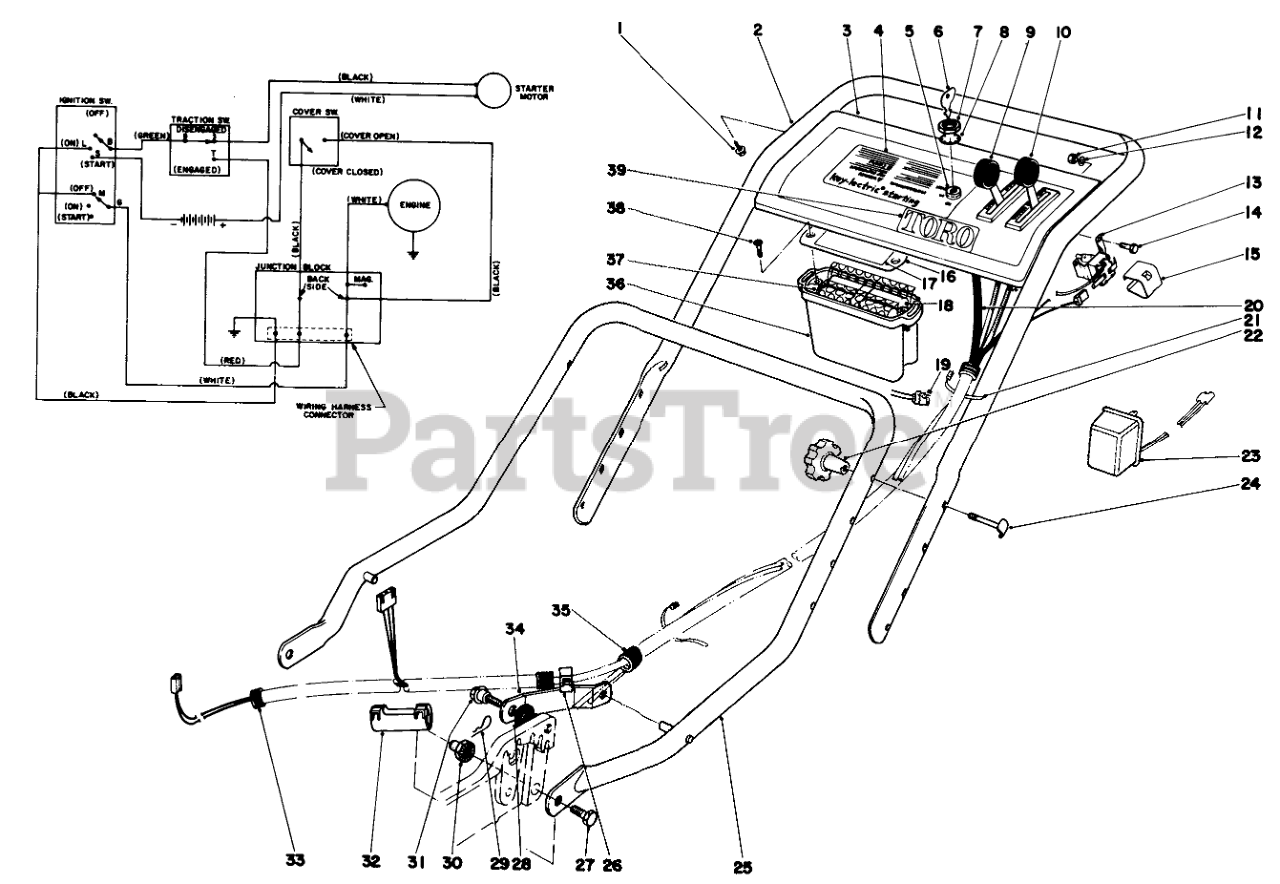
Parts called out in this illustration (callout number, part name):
1	SCREW-HWHTF
2	Upper Handle
3	Control Plate
4	Decal Control Plate
5	SWITCH-STARTER
6	Key
7	NUT-HH
8	WASHER-TOOTH, INTERNAL
9	Throttle Control
10	Control-Traction
11	NUT-HEX
12	WASHER-FLAT
13	CONTROL SWITCH
14	SCREW-HH
15	Cover Switch
16	Cover
17	Decal Battery
18	Battery Pack Assembly (Incl. Ref. #16-19 & 36-38)
19	Plug & Wire
20	Wiring Harness
21	TIE-CABLE
23	Charger
24	HANDLE SCREW
25	Lower Handle
26	RING FITTING
27	SCREW-HH
28	SPACER
29	PIN-COTTER, HAIR
30	HANDLE PIVOT NUT
31	SCREW-SHOULDER
32	Breakout Fitting
33	WIRING HARNESS COVER
34	HANDLE LATCH
35	Upper Wiring Harness
36	Container Pack
37	Spacer
39	TORO LOGO DECAL
